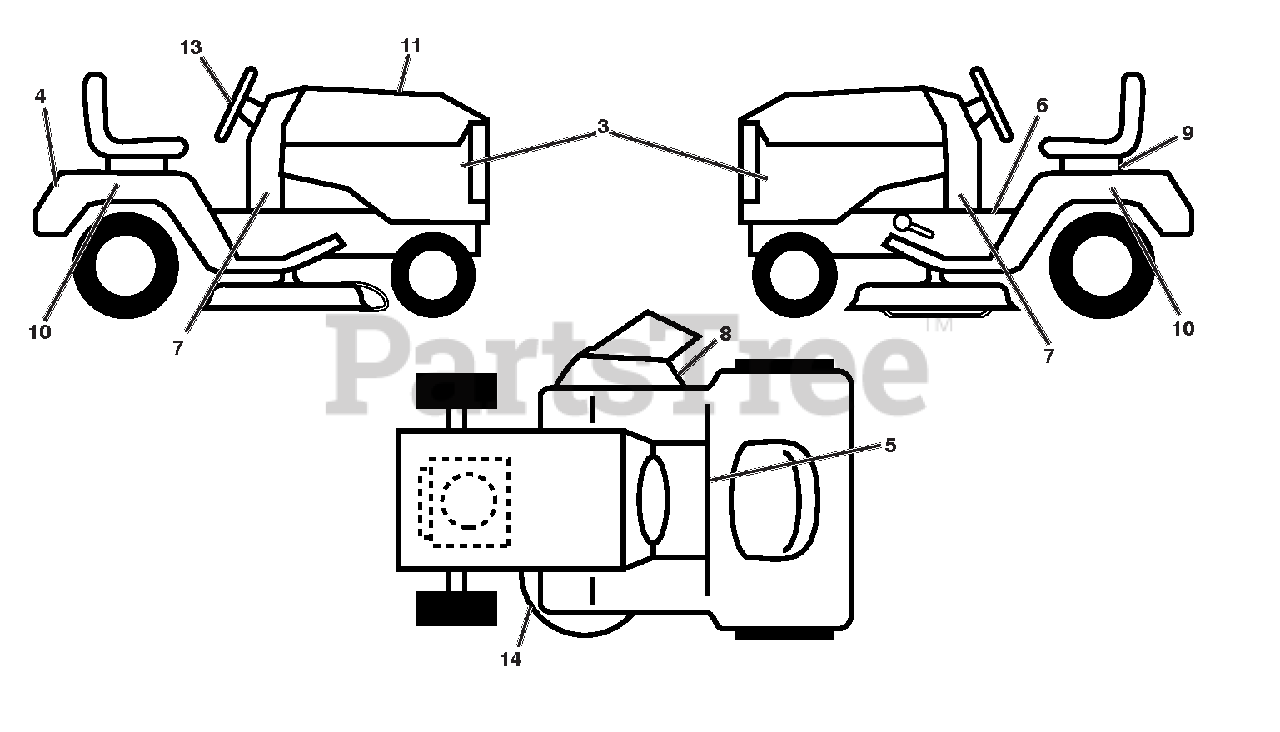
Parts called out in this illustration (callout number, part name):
3	DECAL.SDPNL.PWRDBY KOHL.ARIENS
4	DECAL.FENDER.REAR.ARIENS
5	DECAL.FENDER
6	DECAL, WARNING START INST.
7	DECAL.DASH.LWOWER.20HP.ARIENS
8	DECAL.MOWER.WARN.KEEP HAND AWY
9	DECAL.BAT.DAN/POI P/L SYM.WPN
10	DECAL.FENDER.SIDE.HYDRO.ARIENS
11	DECAL REPLACEMENT
13	DECAL.WHEEL.STEER.ARIENS
14	DECAL.V-BELT.SCH.42/46"MEC/ELE
